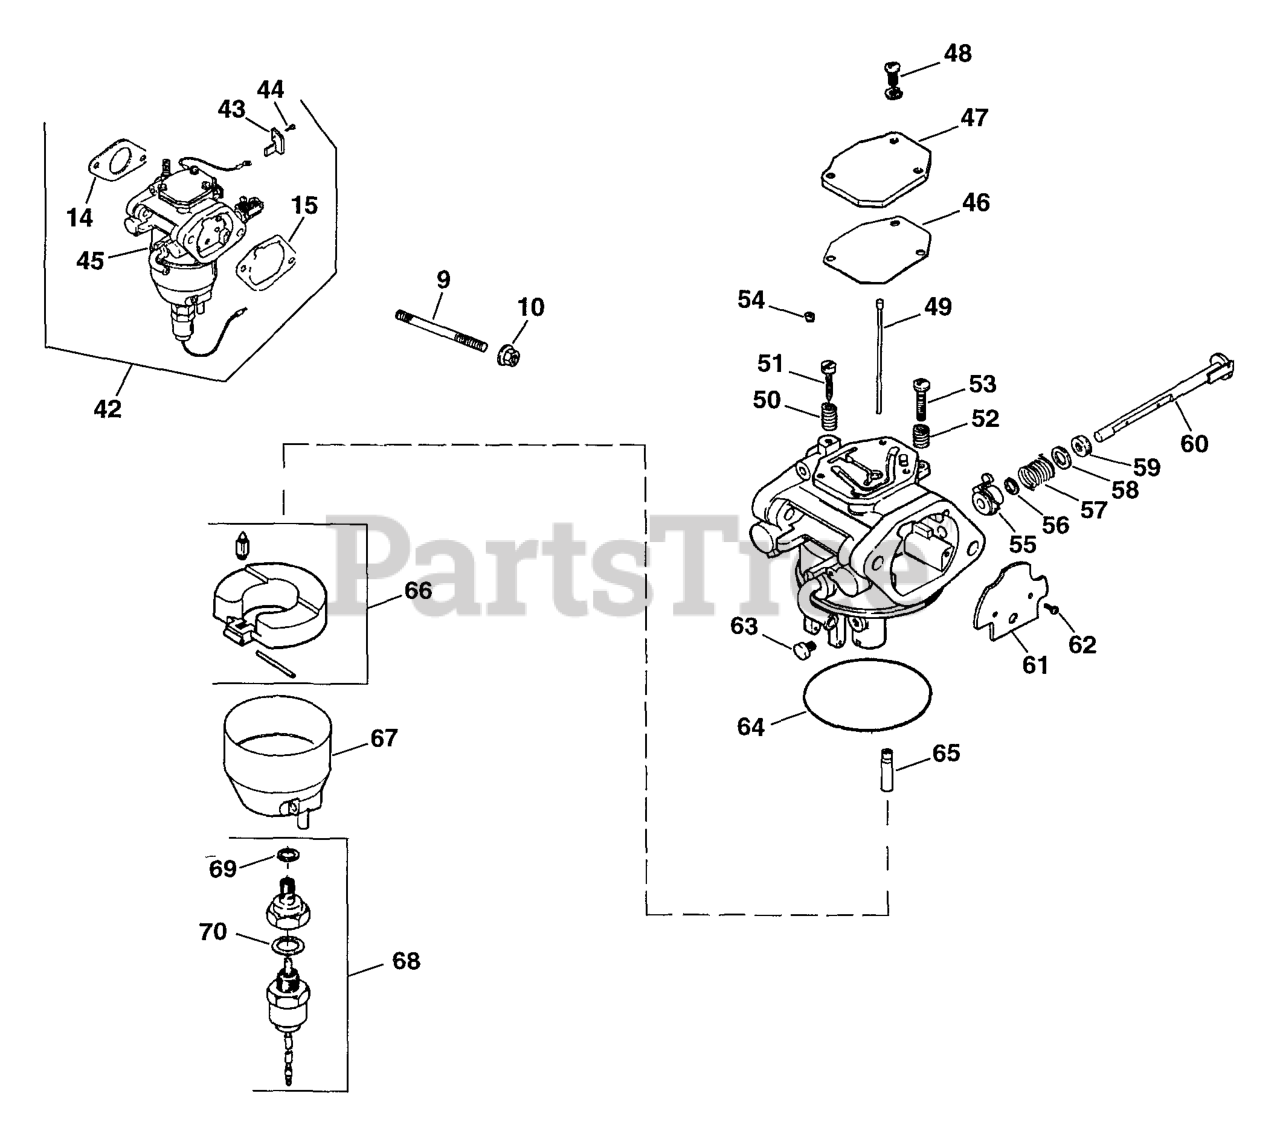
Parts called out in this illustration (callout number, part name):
9	Stud, M6x1.0x128
10	Nut, Hex. M6x1.0
14	Gasket, Carburetor
15	Gasket, Air Cleaner Base
45	Carburetor Assembly
46	Gasket, Passage Cover
47	Cover, Passage
48	Screw, Sems Pan Hd. M4x0.7x8
49	Jet, Slow
50	Spring, Idle Adjusting Screw
51	Screw, Idle Adjusting
52	Spring, Throttle Adjusting Screw
53	Screw, Throttle Adjusting
54	Jet, Air Bleed
55	Lever, Choke
56	Ring, Choke Lever
57	Spring, Choke Return
58	Collar, Choke
59	Washer, Felt 5.7 Mm
60	Shaft, Choke
61	Valve, Choke
62	Screw, Sems Pan Hd. M3x0.5x4.5
63	Jet, Main
64	Gasket, Float Chamber
65	Nozzle, Main
66	Kit, Float
67	Chamber, Float (Bowl)
68	Kit, Solenoid Valve
69	Gasket, Chamber Screw
70	Gasket, Solenoid
